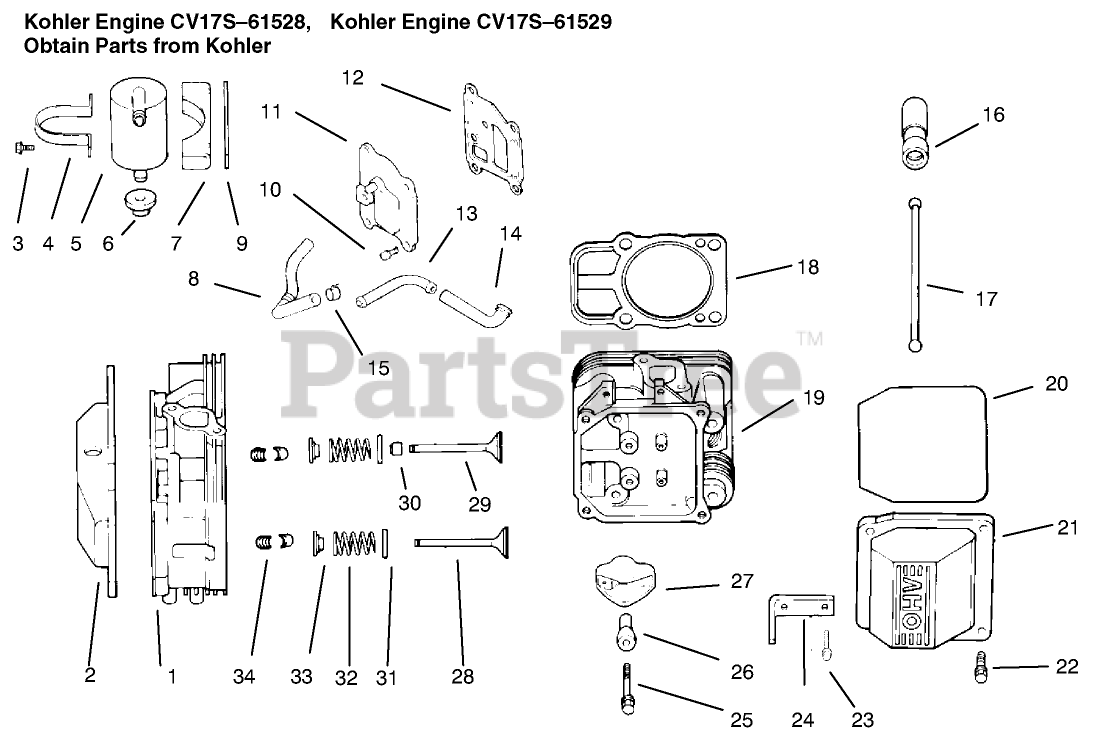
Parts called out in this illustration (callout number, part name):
1	Head ASM-#1 Cylinder (Only On: 72103, 72083)
2	Kit-Valve Incl 6 20-22
3	Screw M5x0.8x16 (Only On: 72042, 72063, 72062, 72043)
4	Strap-Lifting
5	Kit-Breather Incl 3-9
6	Grommet-Rubber (Only On: 72103)
7	Bracket
8	Hose-Breather
11	Cover-Breather (Only On: 72103)
12	Gasket-Breather
13	Fitting
14	Hose-Breather
15	Clamp
16	Lifter-Valve
17	Rod-Push
18	Gasket-Cylinder Head
19	Head ASM-#2 Cylinder (Only On: 72103, 72083)
21	Kit-Valve Cover (Incl. Ref. #2 3)
22	Screw-Shoulder
23	Screw
24	Strap-Lifting
26	Pivot-Arm, Rocker
27	Arm-Rocker
28	Valve-Exhaust
28	Valve-Exhaust (.25)
29	Valve-Intake
29	Valve-Intake (.25)
30	Seal-Valve Stem
31	Retainer-Spring
32	Spring-Valve
33	Cap-Valve Spring
34	Kit-Retainer
